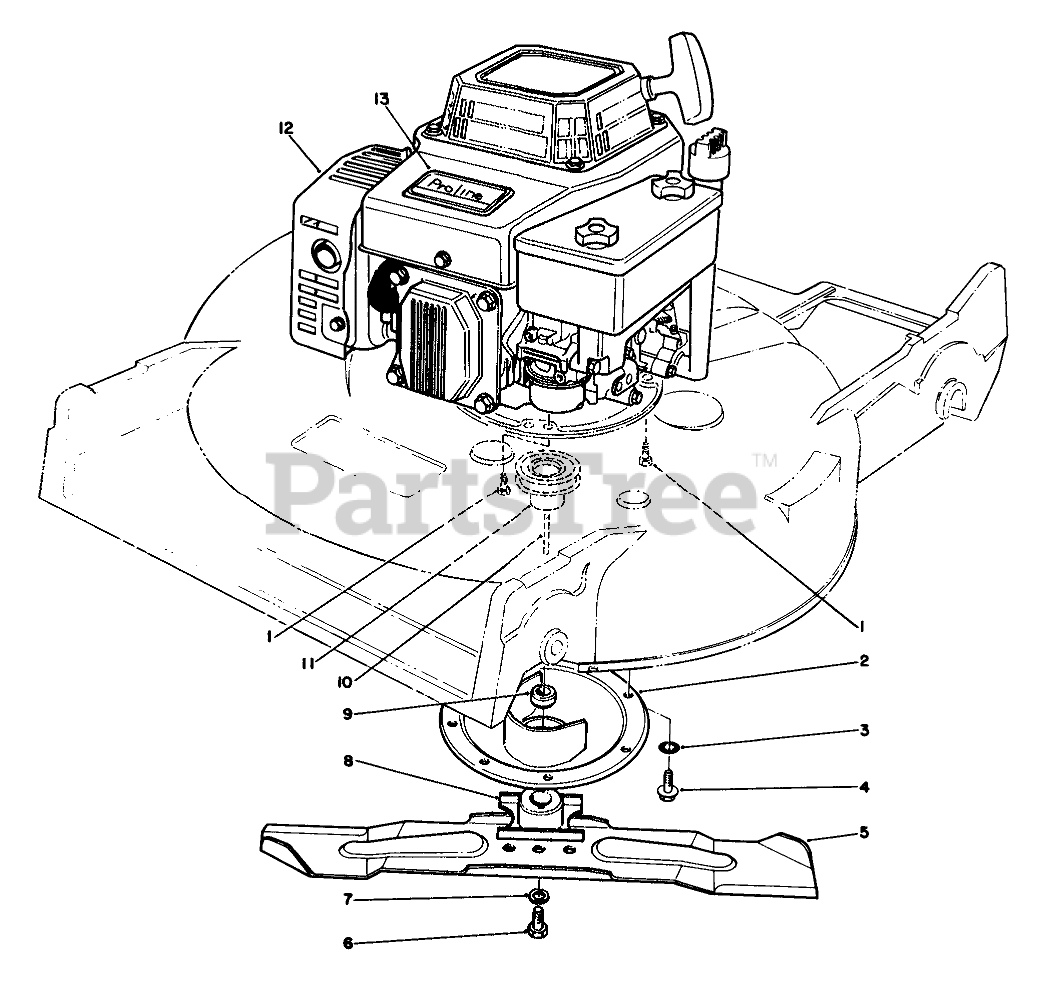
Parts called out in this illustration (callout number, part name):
1	SCREW-HWHTF
2	PROTECTOR-CRANKSHAFT
3	WASHER-LOCK, INTERNAL
4	SCREW-HWHTF
5	BLADE-21in
6	SCREW-BLADE
7	WASHER-LOCK
8	RETAINER-BLADE
9	SPACER-BLADE RETAINER
10	KEY-SQUARE
11	PULLEY-DRIVER
13	DECAL - PROLINE
